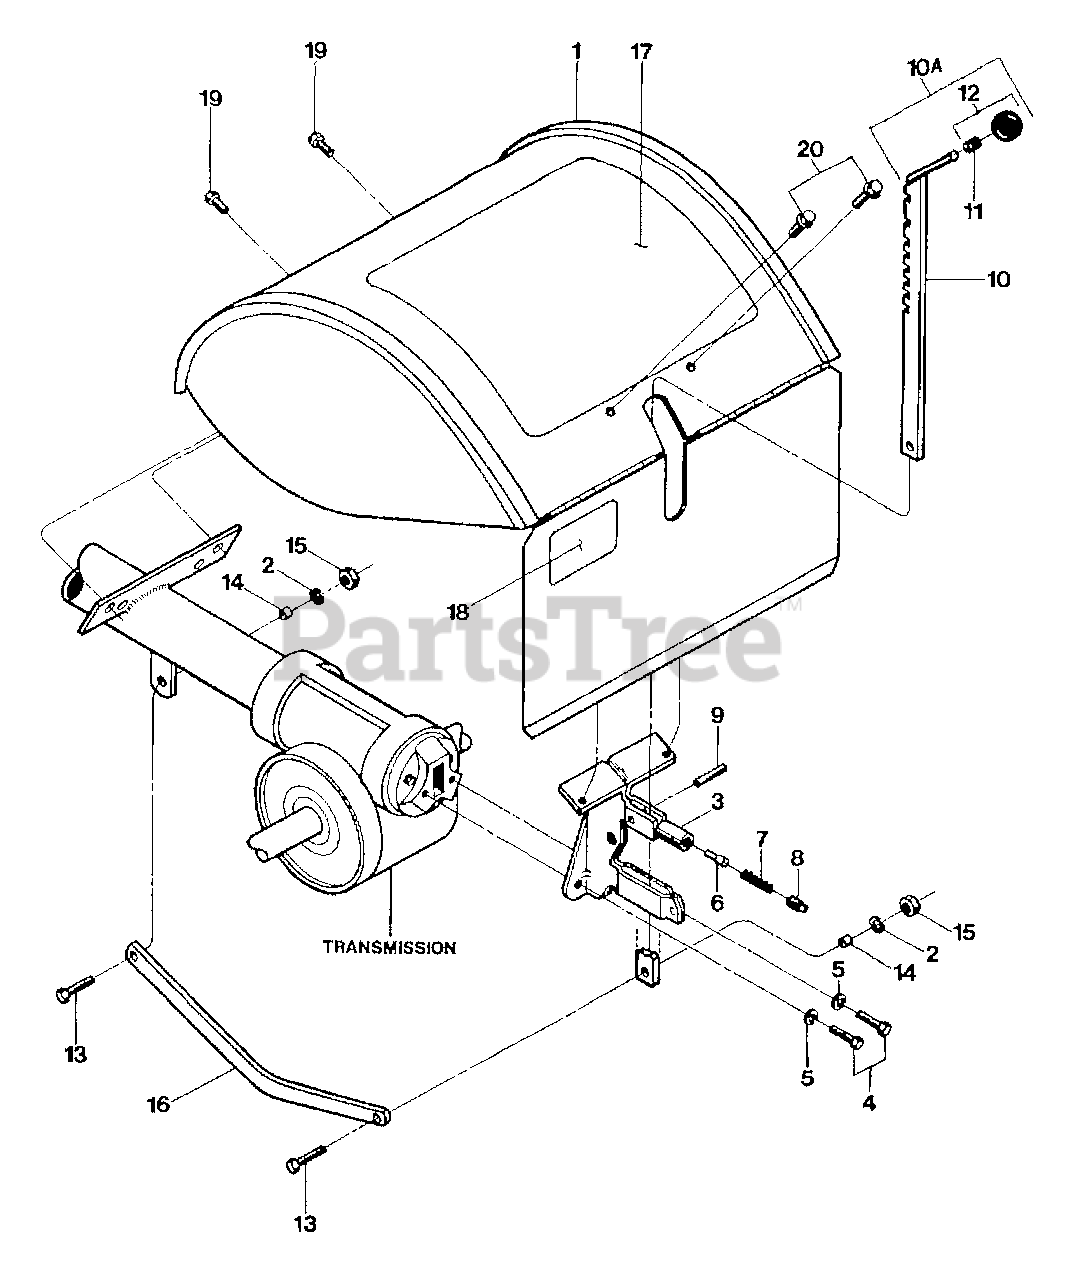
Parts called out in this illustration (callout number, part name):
1	HOOD W/DECALS-ECONO(INCL. DECALS 2503 & 2504)
2	WASHER-LK .375 @ DEPL
3	KIT-REAR HOOD BRKT
4	SCR-HHC 5/16-18X.75 GR 5 ZP (BRACKET TO REAR BEARING CAP)
5	WASHER-LK .312 ZP
6	PLUNGER
7	SPRING .406 X 1.25
8	PLUG-PIPE 1/4 NPT
9	PIN-ROLL .25 X 1 (SPIRAL)
10	BAR - DEPTH ADJUSTMENT (NOT AVAIL. SEP. SEE 10A)
10A	DEPTH REGULATOR W/KNOB (INCL. 10,11,12)
11	RING-TOLERANCE .5325 ID
12	KNOB-CONTROL (INCL. 11)
13	SCR-HH 3/8-16X1.25
14	BUSHING-.5X.375X.3
15	NUT-HEX 3/8-16 ZP
16	DRAG BAR-BENT
17	DECAL-OPER INST
18	DECAL-HOOD LOGO ECONO (MODEL NAME DECAL)
19	SCR-HWH 5/16-18 X .5 STH
20	SCR-HWH 1/4-20 X .5 STH (ATTACHES HOOD TO DEPTH REGULATOR BRACKET)
